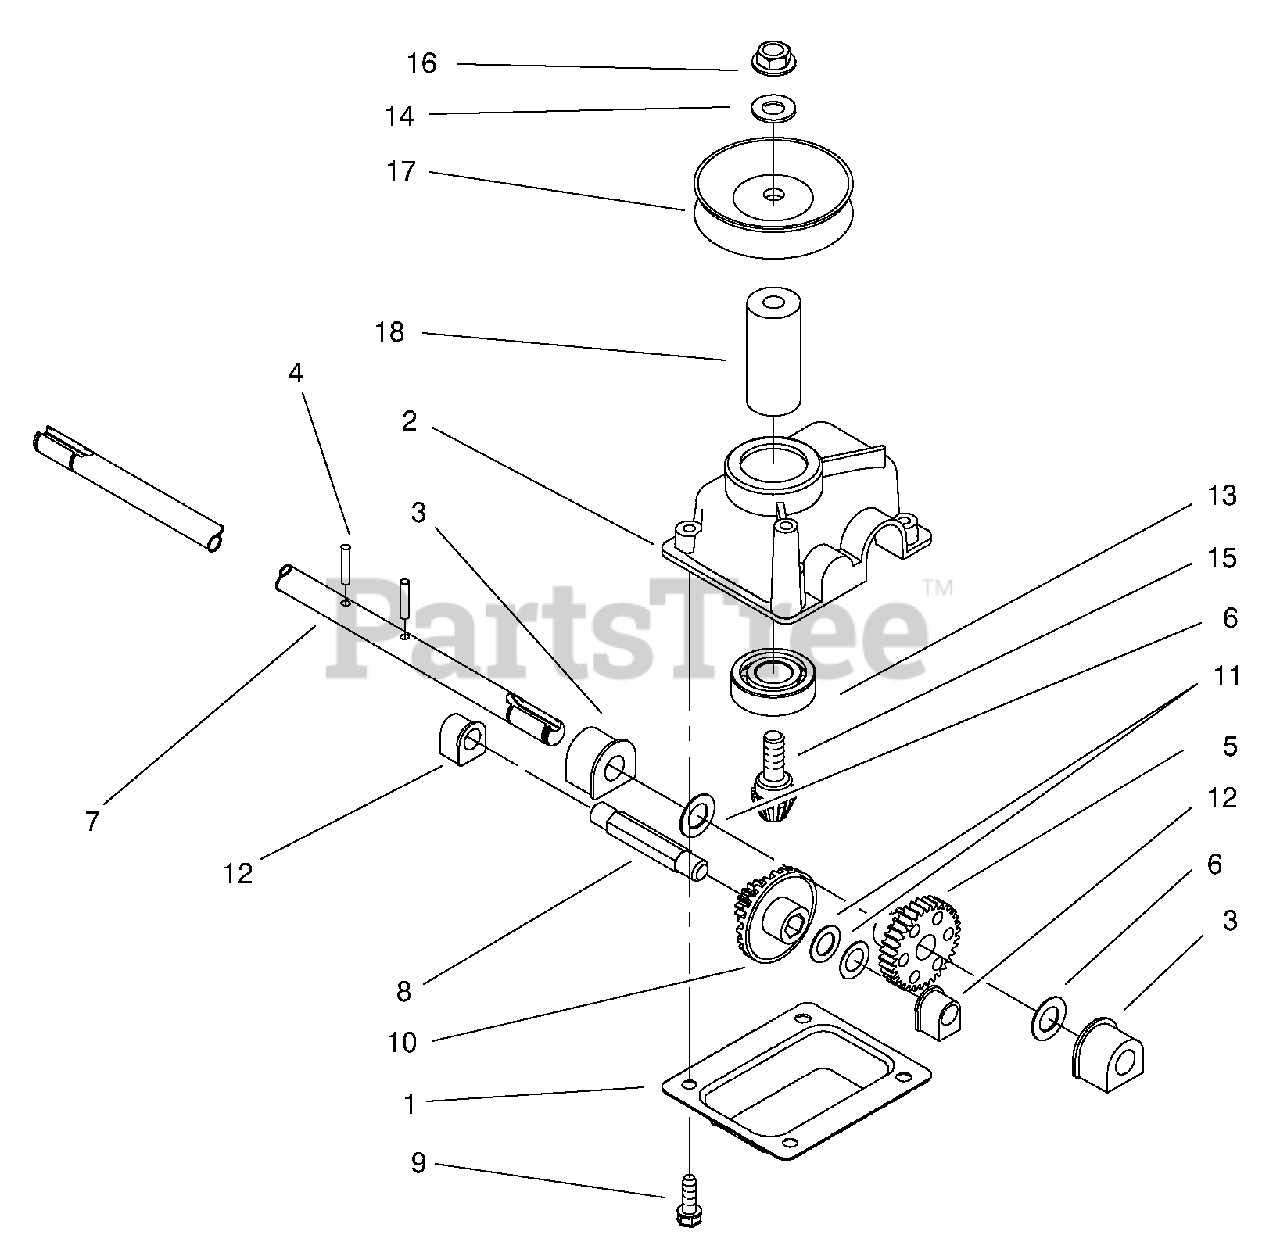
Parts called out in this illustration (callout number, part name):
1	Cover-Gear Case
2	Gearcase-Upper Ss
3	Bushing-Output
4	Pin-Spirol
5	Gear-34t
6	Washer-Thrust
7	Shaft-Output
8	Shaft-Intermediate
9	Screw-TAP
10	15 T Pinion
11	Washer-Thrust
13	Bearing-Ball
14	Washer-Flat
15	Gear-Pinnion
16	Nut-Lock
17	Pulley-Half
18	Spacer-pulley
